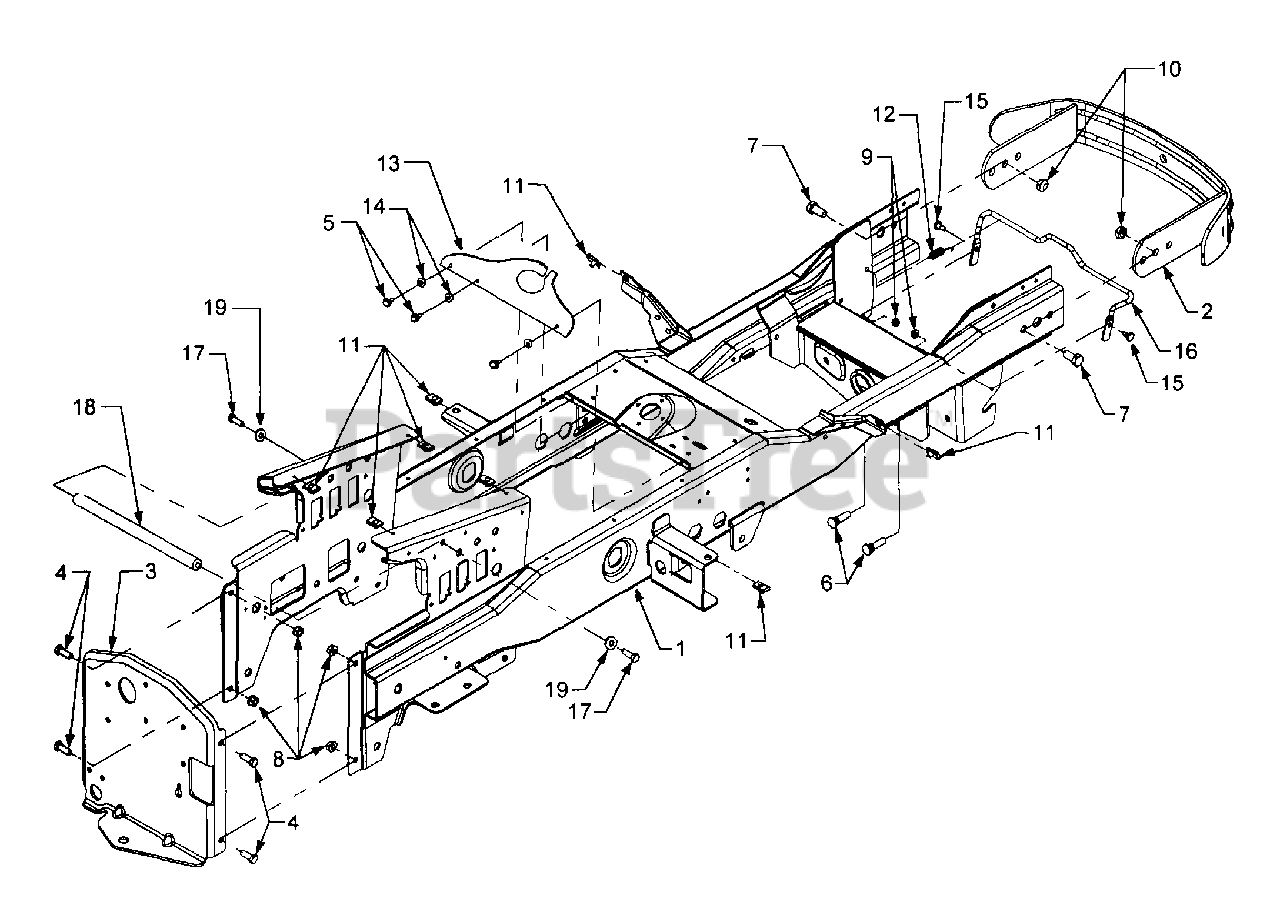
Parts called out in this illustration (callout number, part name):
1	Frame Assembly
2	Bumper, Front
4	Screw, Hex Cap 3/8-16 x 1.0 GR5
5	Screw, Hex Wash. Hd. Tapp 1/4-20 x .5
6	Screw, Round Hd., 3/8-24
7	Screw, Hex Cap 1/2-13 x 1.0 GR5
8	Nut, Hex Flange Lock, 3/8-16
9	Nut, Hex Flange Lock, 1/4-20
10	Nut, Hex Lock, 1/2-13
11	Speed Nut, U-Type, 5/16-18
12	Spring, Extension
13	Flap, Intk.
14	Washer, Flat, .283 x .75 x .030
15	Shoulder Screw, .312 x .18
16	Rod, Front Latch
17	Screw, Hex Cap, 5/16-18 x .875
18	Shaft, Frame Brace
19	Washer, Flat, .344 x .75 x .12
